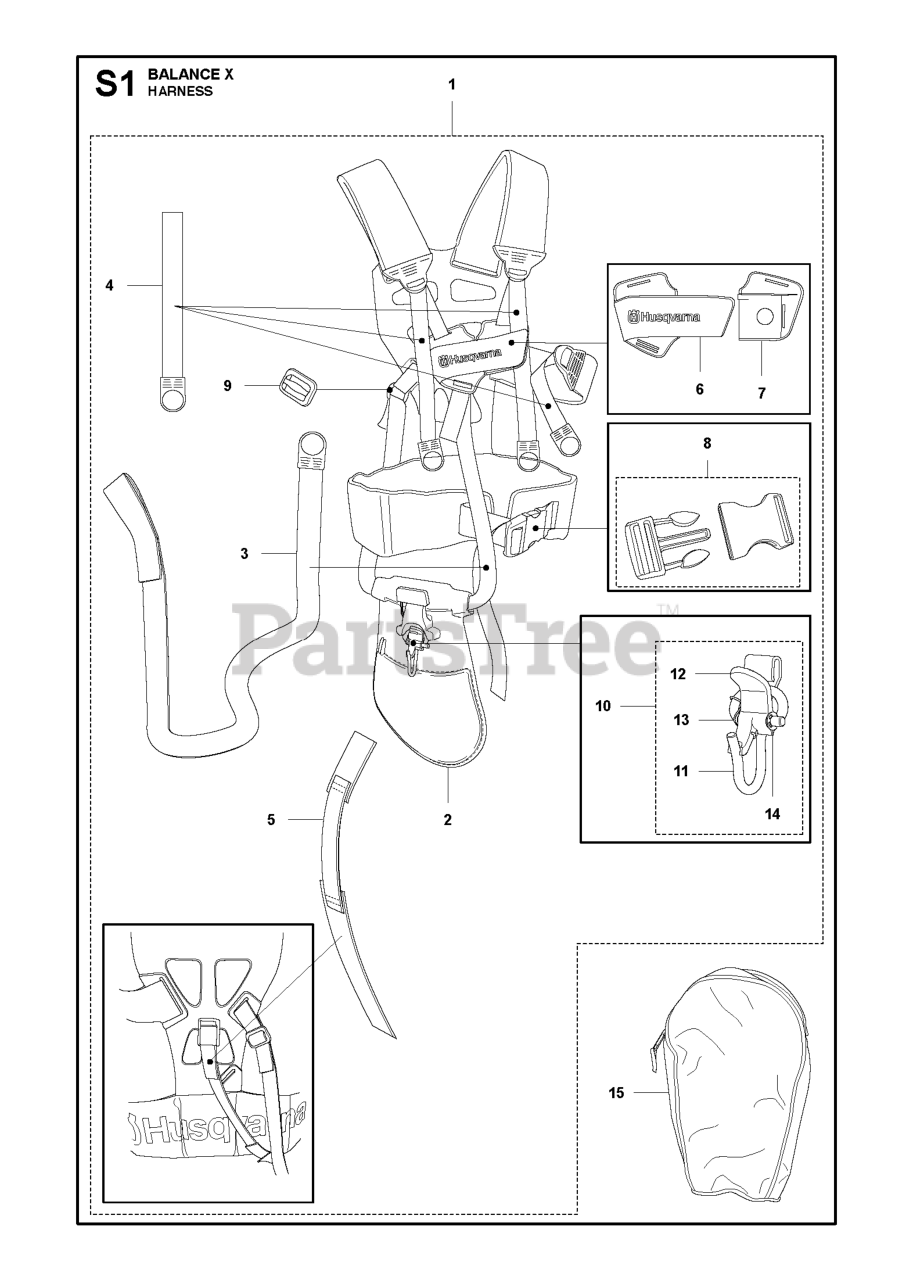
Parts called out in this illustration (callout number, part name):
1	HARNESS BALANCE X
6	FRONT PIECE
7	FRONT PIECE
11	HOOK
12	CATCH *
13	SPRING LOCKING
15	TOOL BAG
